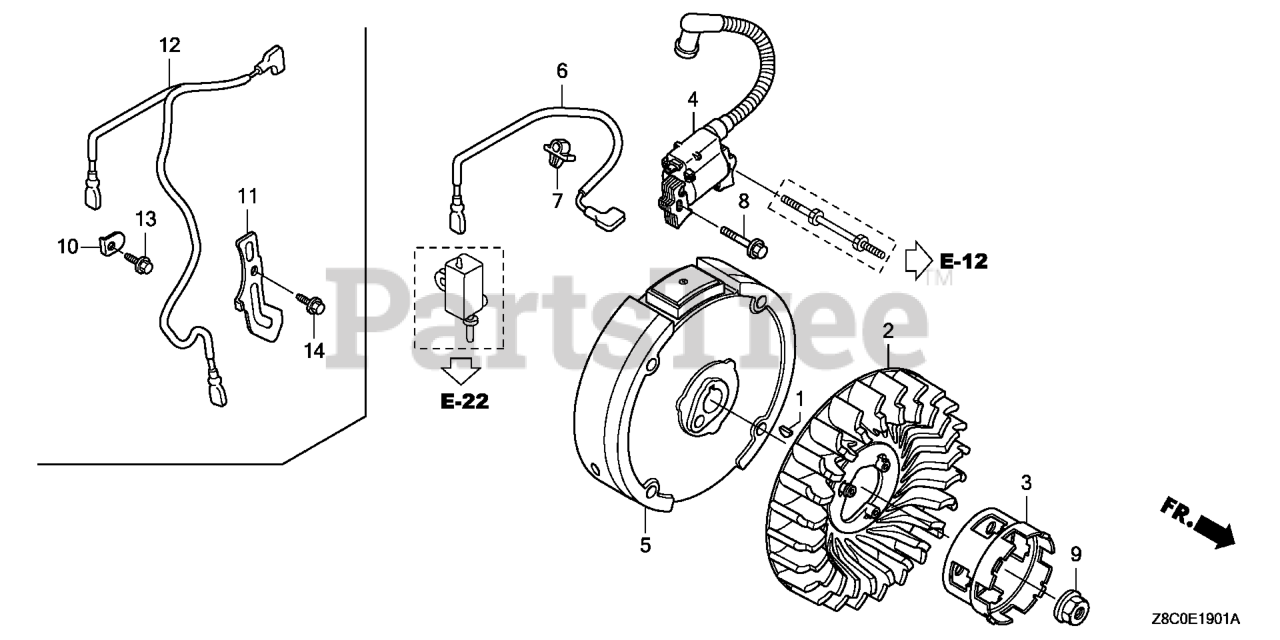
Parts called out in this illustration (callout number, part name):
1	KEY, SPECIAL WOODRUFF (25X18)
2	FAN, COOLING
3	PULLEY, STARTER
4	COIL ASSY., IGNITION (PHELON)
5	FLYWHEEL
8	BOLT, FLANGE (6X23)
9	NUT, SPECIAL (14MM)
